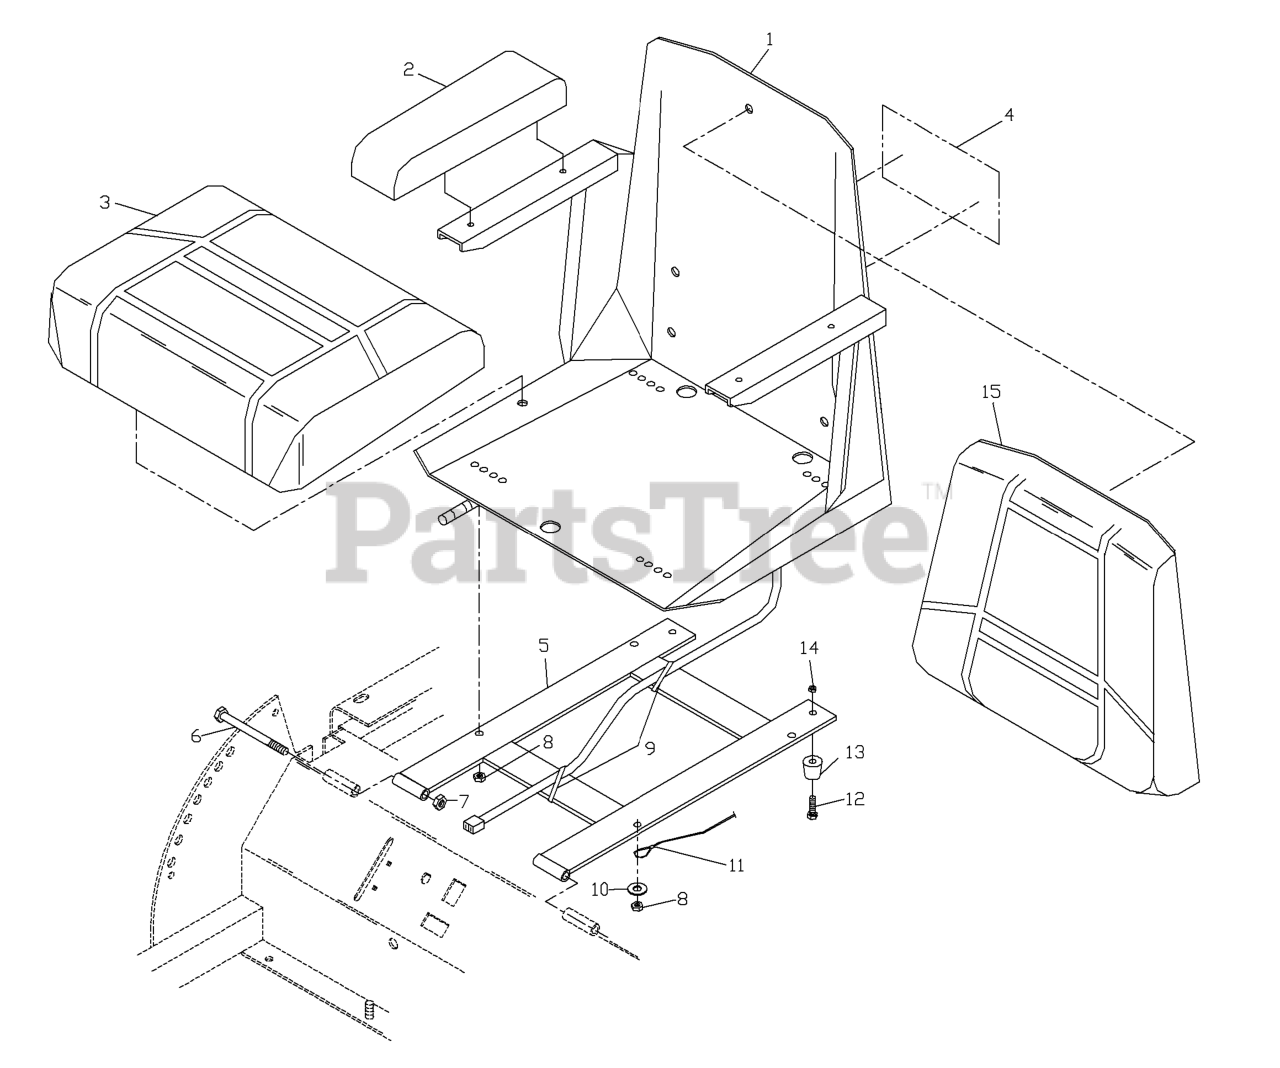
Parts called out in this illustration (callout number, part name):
1	SEAT, COMPLETE
2	ARM REST CUSHIONS/PAIR
3	SEAT CUSHION W/SWITCH
4	DECAL, CROWN H
5	SEAT MOUNT
6	HCS 3/8C X 4 1/2
7	NUT 3/8C CENTERBLOCK
8	NUT 5/16C CENTERLOCK
9	TIE, PLASTIC
10	WASHER 5/16 FLAT
11	SEAT LANYARD
12	SCREW, #1--24 X 1/2 SLOTTED
13	SEAT BUMPER
14	NUT 10-24 NYLOC
15	SEAT, BACK CUSHION
